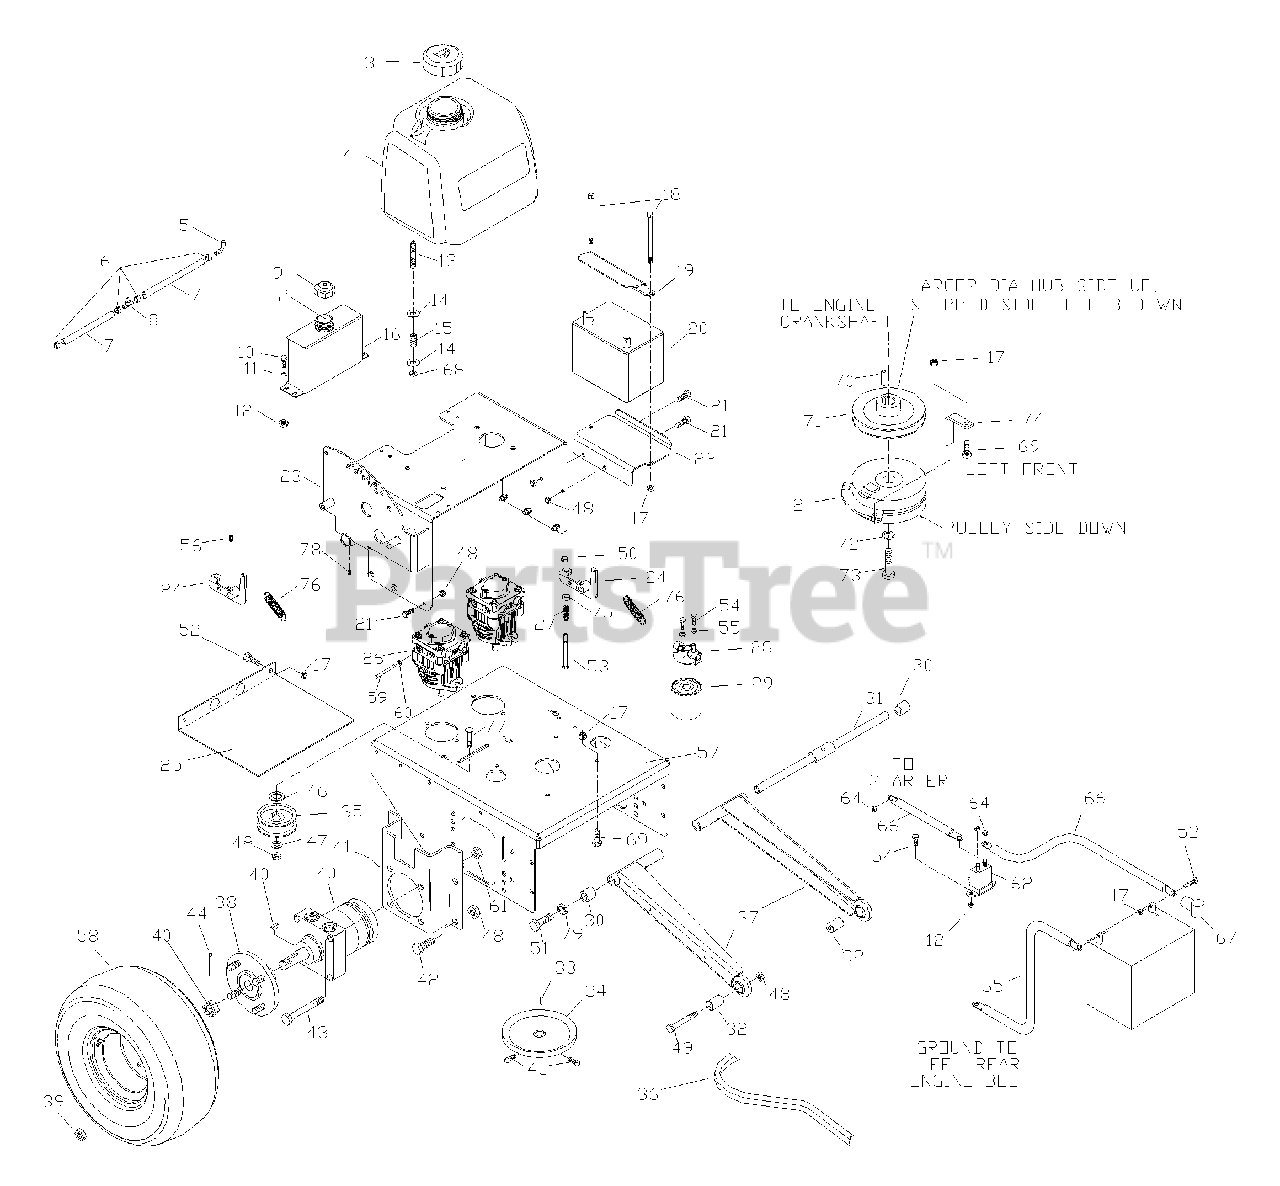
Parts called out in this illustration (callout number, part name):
1	THROTTLE CABLE
3	FUEL CAP
5	FUEL FITTING
6	HOSE CLAMP
8	FUEL VALVE
10	HCS 1/4 X .750
11	WASHER 1/4 FLAT
12	NUT 1/4 CTR. LOCK
14	WASHER 5/16 FLAT
17	NUT 5/16 CTR. LOCK
18	HCS 5/16 X 7.000
19	BATTERY STRAP
20	BATTERY
21	HCS 3/8 X .750
22	BATTERY TRAY
23	TANK SUPPORT
25	BELT SHIELD
26	PUMP
28	FILTER HEAD
31	STRUT SHAFT
32	SPACER, FRONT
33	KEY, METRIC
35	IDLER PULLEY
40	HYD. MOTOR
41	MOTOR MOUNT
42	HFCS 1/2 X 1.250
43	HCS 3/8 X 2.750
44	COTTER PIN
45	SET SCR. 5/16
46	WASHER 1/2 FLAT
47	WASHER 3/8 FLAT
48	NUT 3/8 CTR. LOCK
49	HCS 3/8 X 2.250
50	NUT 3/8 NYLOC
51	HCS 1/2 X 1.00
52	HCS 5/16 X .750
53	HCS 3/8 X 2.750
54	HCS 1/4 X .625
55	WASHER 1/4 LOCK
56	SET SCR. 5/16
58	TIRE /WHEEL ASM.
58	RIM
59	CLEVIS PIN
61	NUT 1/2 NYLOC
64	NUT 1/4 NYLOC
66	POS. CABLE
68	NUT 5/16 NYLOC
69	HCS 5/16 X 1.750
70	KEY 1/4 X 1.125
72	WASHER 7/16 LOCK
73	HCS 7/16 X 2.500
77	RHSNB 3/8 X 2.000
78	ZERK
79	WASHER 1/2 LOCK
